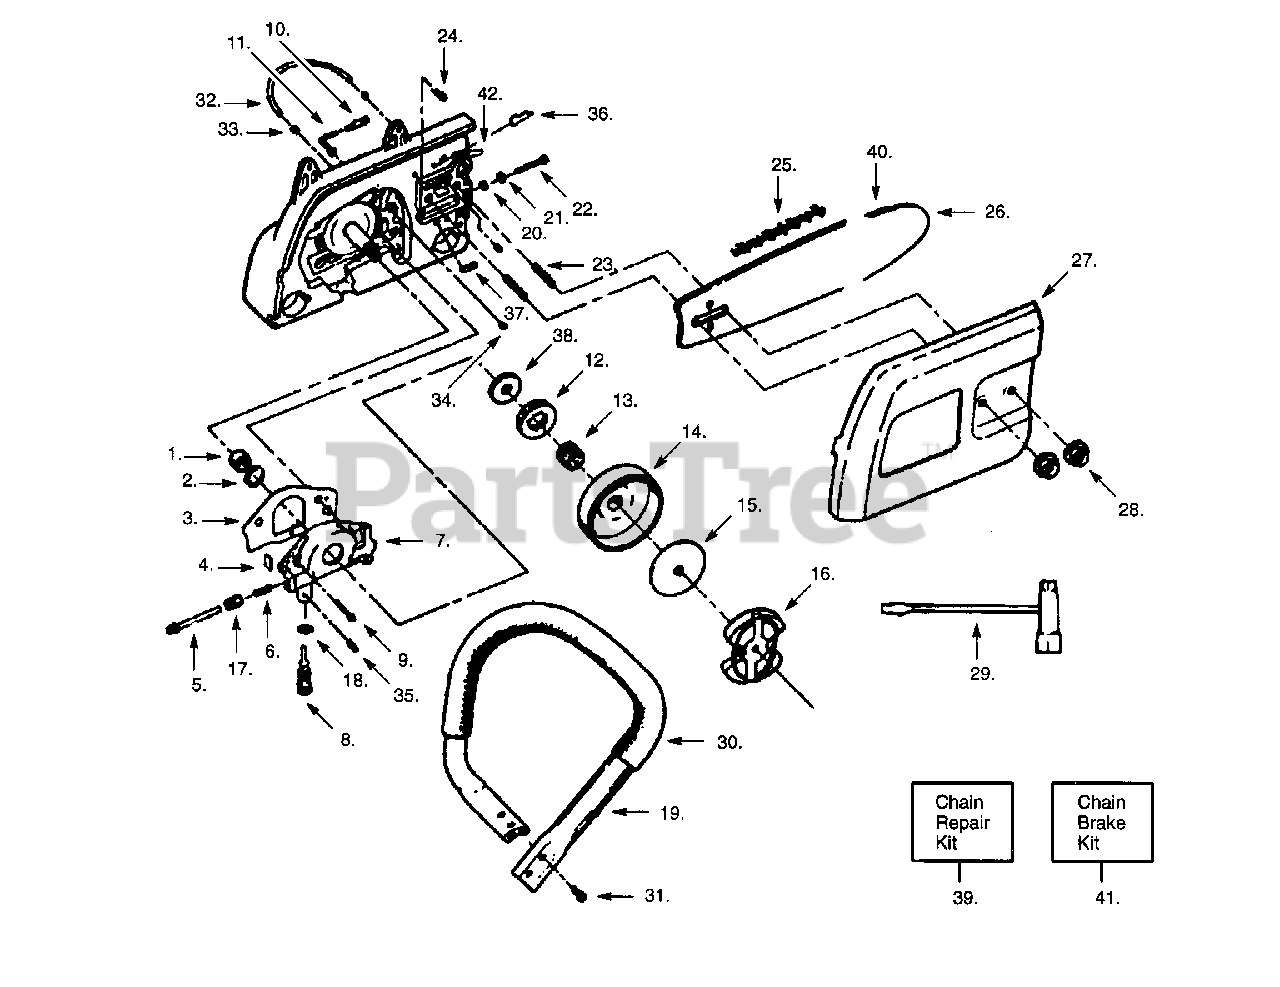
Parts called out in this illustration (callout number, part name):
1	Worm Gear
3	Gasket Set
4	Dust Plug
7	Oil Pump Kit (Inc.1,2,4-6,8,17,18,35)
9	Screw
10	Oil Pickup & Filter
11	Oiler Intake Line
12	Rim Sprocket-Model 305 & 335
14	Drum Sprocket-Model 285
14	Drum-Model 305&335
15	Clutch Plate
16	Clutch Ass'y.
17	Oiler Gear Spur
18	"O" Ring
19	Model 285
19	Model 305 & 335
20	Bar Adjusting Pin
21	"E" Ring
22	Screw
23	Bar Stud
24	Vent Pin
25	16" (P33S-66)
25	16" (P34S-66)
25	18" (P33S-72)
25	20" (P33S-78)
26	16" SNR (.325-.050P)
26	16" SNR (.325-.058P)
26	18" SNR (.325-.050P)
26	18" SNR (.325-.058P)
27	Bar Clamp (Inc.37.)
28	Nut
29	Scrench
30	Model 285
30	Model 305 & 335
32	Oiler Discharge Line
33	Oiler Discharge Sleeve
34	Tubing Nut
35	Oiler Adjustment Pin
36	Chain Pad-Top
37	Chain Pad
39	Chain Repair Kit
40	Replaceable Sprocket Nose
41	Chain Brake Kit
42	Crankcase Plug
